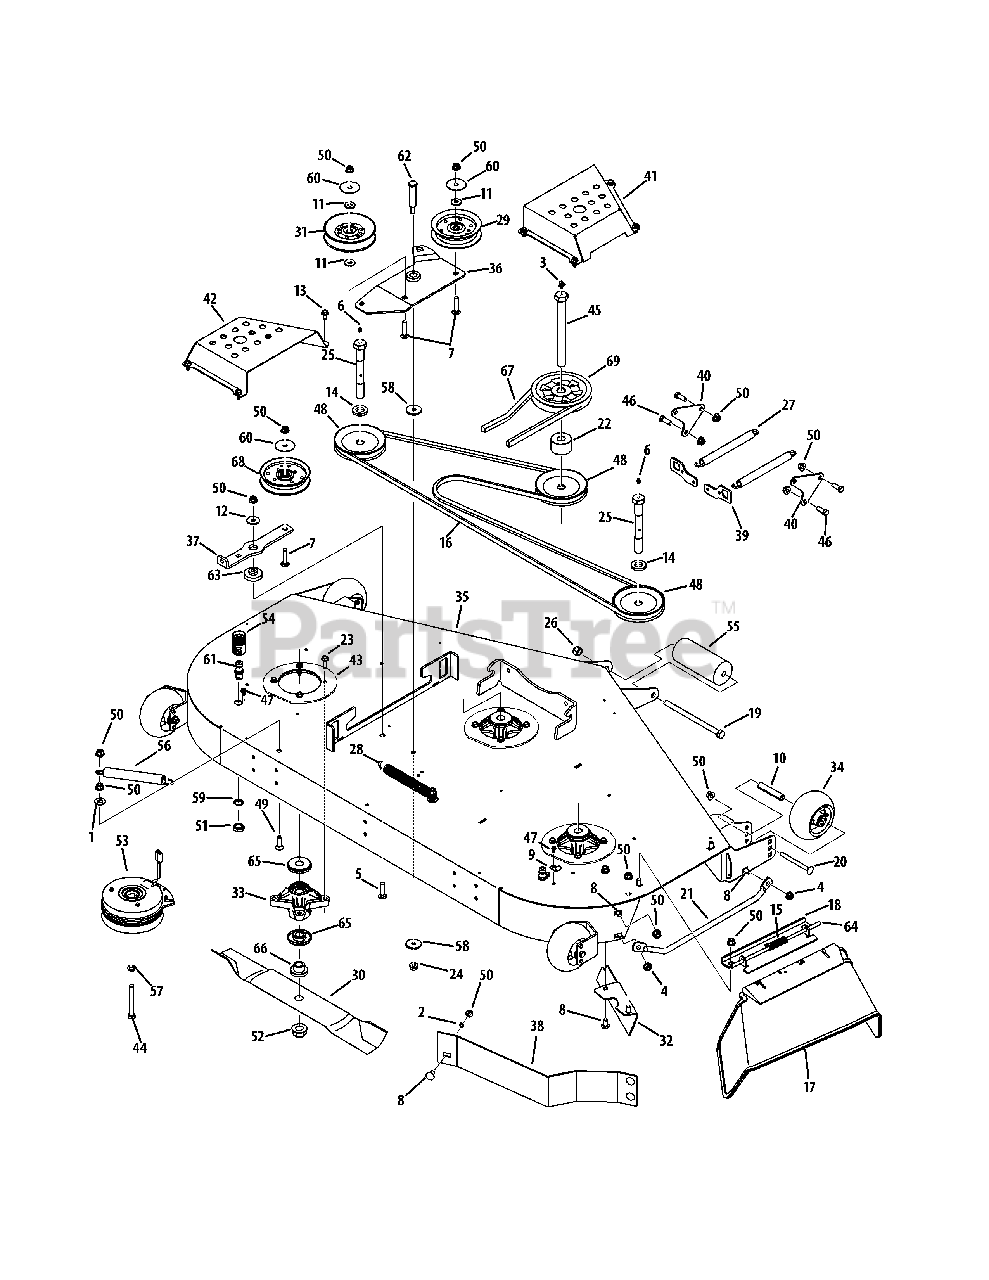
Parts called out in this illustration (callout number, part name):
1	Washer, .532 x 1.06 x .094
2	Retainer Nut
3	Grease Fitting, 1/4-28 x .788
4	Counterlock Flange Nut, 3/8-16
5	Carriage Bolt, 3/8-16 x 1.50
6	Straight Grease Fitting, 1/4-28
7	Carriage Bolt, 3/8-18 x 1.75
8	Carriage Bolt, 3/8-16 x .75
9	Retainer Hook
10	Spacer, .390 x .620 x 3.04
11	Washer, .406 x 1.00 x .105
12	Washer, .411 x 1.25 x 1.00
13	TT Screw, 5/16-18 x .750
14	Spacer, .812 x 1.47 x .218
15	Torsion Spring
16	V-Belt
17	Fab Deck Deflector Chute
18	Deflector Chute Bracket
19	Hex Screw, 1/2-20 x 7.50
20	Carriage Bolt, 3/8-16 x 4.00
21	Fab Deck Chute Finger Guard
22	Spacer, .760 x 2.00 x 1.69
23	Flange Hex TT Screw, 5/16-18 x 1.50
24	Nut, Hexlk, 1/2-20, Gr2, Nylon
25	Hex Screw, 3/4-16 x 6.00
26	Nylock Nut, 1/2-20
27	Hook Ext. Spring, .75 x 7.89 x .14
28	Hook Ext. Spring, .94 x 7.57 x .14
29	Idler Pulley, 4.88
30	Hi-Lift Blade, 21.0
31	Idler Pulley, 5.06
32	Deck Chute Baffle
33	Spindle Assembly
34	Deck Wheel
35	60" Welded Deck
36	60" Idler Assembly
37	Deck Idler Arm
38	Standard Baffle
39	Spring Mount Bracket
40	Spring Mount Plate
41	60" RH Belt Cover
42	60" LH Belt Cover
43	Spindle Reinforcement Plate
44	Hex Screw, 7/16-20 x 3.50
45	Hex Screw, 3/4-16 x 8.0
46	Hex Screw, 3/8-16 x 1.00
47	Hex Washer TT Screw, 1/4-20 x .500
48	V-Type Pulley
49	Carriage Bolt, 3/8-16 x 1.25
50	Flange Lock Nut, 3/8-16
51	Hex Nut, M16-1.5
52	Flange Lock Nut, 3/4-16
53	Electric PTO Clutch
54	Water Nozzle Adapter
55	Front Roller
56	Extension Spring, .91 x 7.33
57	Lock Washer, 7/16
58	Flat Washer, .390 x 1.500 x .134
59	Lock Washer, 17 x 23.8 x 1.95
60	Flat Washer, .406 x 1.92 x .060
61	Water Deck Nozzle
62	Shoulder Bolt, 3/8-16 x .74 x 2.47
63	Shoulder Spacer, .854 x .280
64	Chute Deflector Rod
65	Deck Spindle Spacer
66	Spindle Spacer, .76 x 2.0 x 1.1
68	Idler Pulley, 4.25
69	V-Type Pulley
